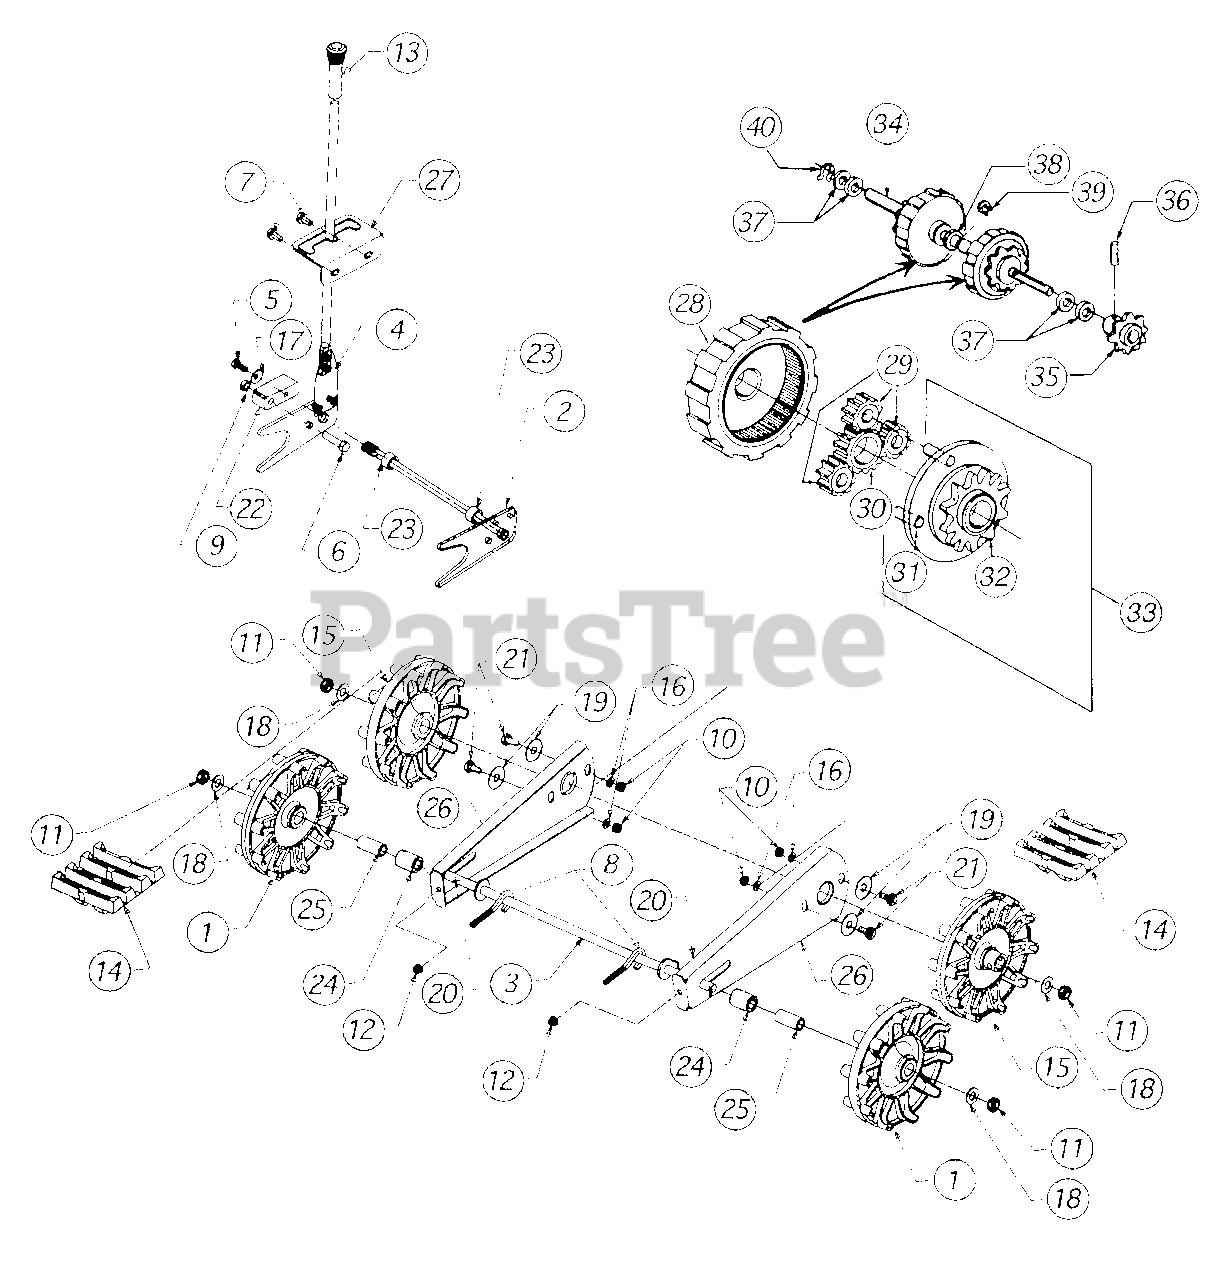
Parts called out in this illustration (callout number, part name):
1	Wheel Assembly Idler
5	Screw
6	Screw
7	Screw
8	Screw
9	Lock Nut
10	Hex Nut
11	Jam Nut
12	Hex Nut
14	Track
15	Wheel - Track Drive
16	Lock Washer
17	Bell Washer
18	Flat Washer
19	Flat Washer
20	Lubricant
21	Shoulder Screw
22	Lift - Shaft Drive
23	Spacer
24	Spacer
25	Spacer
26	Plate - Track Side
28	Gear Ring
29	Gear 12-Tooth
30	Gear 18-Tooth
31	Pin Dowel
32	Carrier
33	Carrier Assembly
34	Shaft - Track Drive
35	Sprocket - 13 Tooth
36	Spring Pin
37	Flat Washer
38	Flat Washer
39	Snap Ring .625" Shaft
40	Snap Ring .56" Shaft
